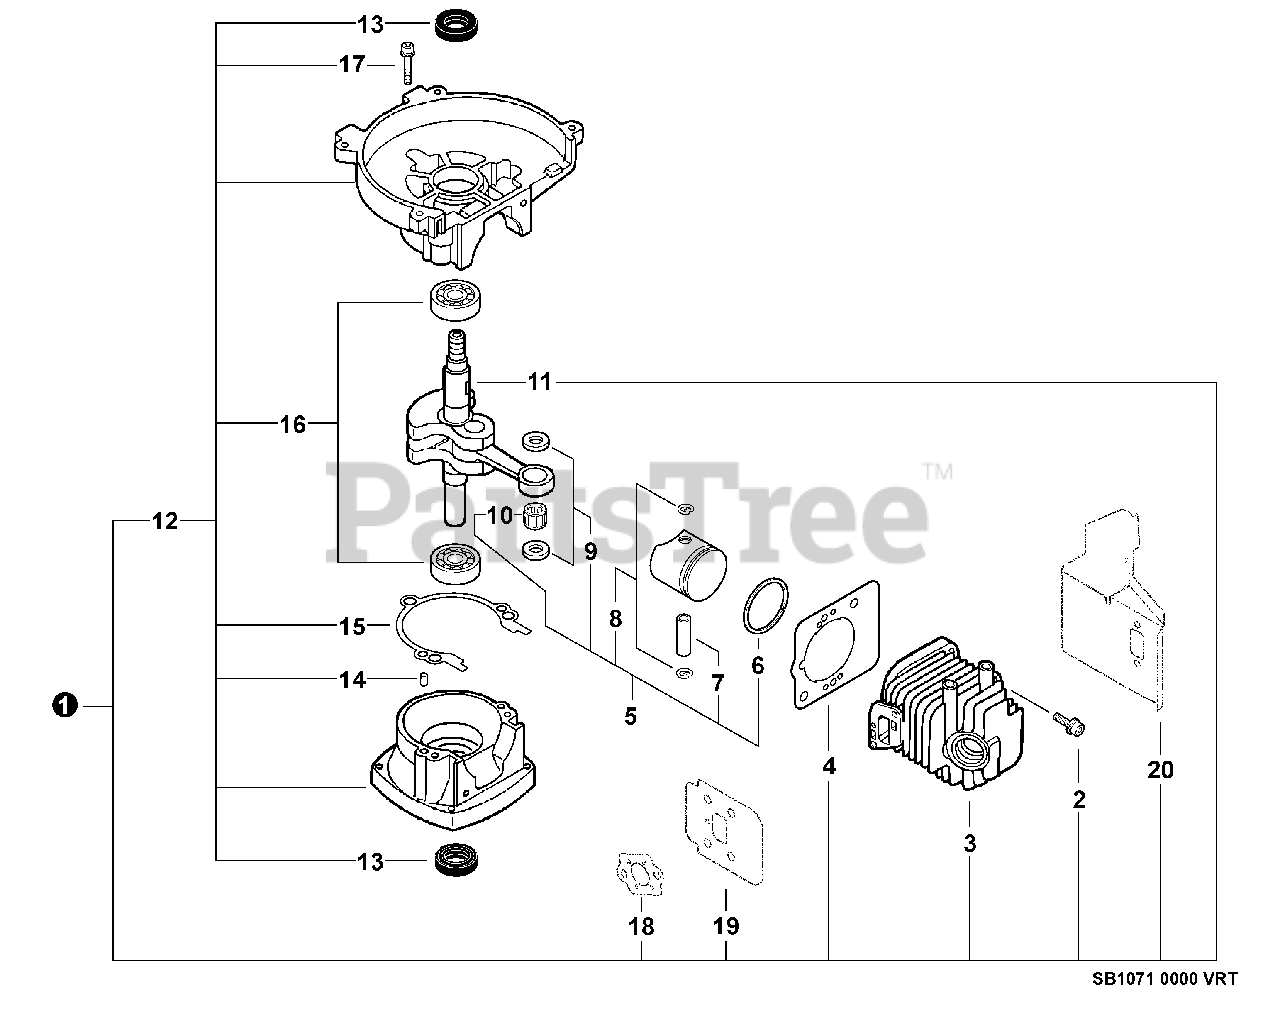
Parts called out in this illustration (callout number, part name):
1	SHORT BLOCK -- SB1071
2	SCREW - 5X22
3	CYLINDER
4	GASKET, CYLINDER
5	PISTON KIT
6	RING, PISTON
7	PIN, PISTON
8	RING, RETAINING
9	SPACER, PISTON
10	CRANKSHAFT ASSY
11	BEARING, NEEDLE - 8
12	CRANKCASE KIT
13	SEAL, OIL
14	PIN - LOCATING
15	GASKET, CRANKCASE
16	BEARING, BALL - 6201
17	SCREW - 5X28
18	GASKET, INTAKE
19	SHIELD, INTAKE
20	SHIELD, EXHAUST
